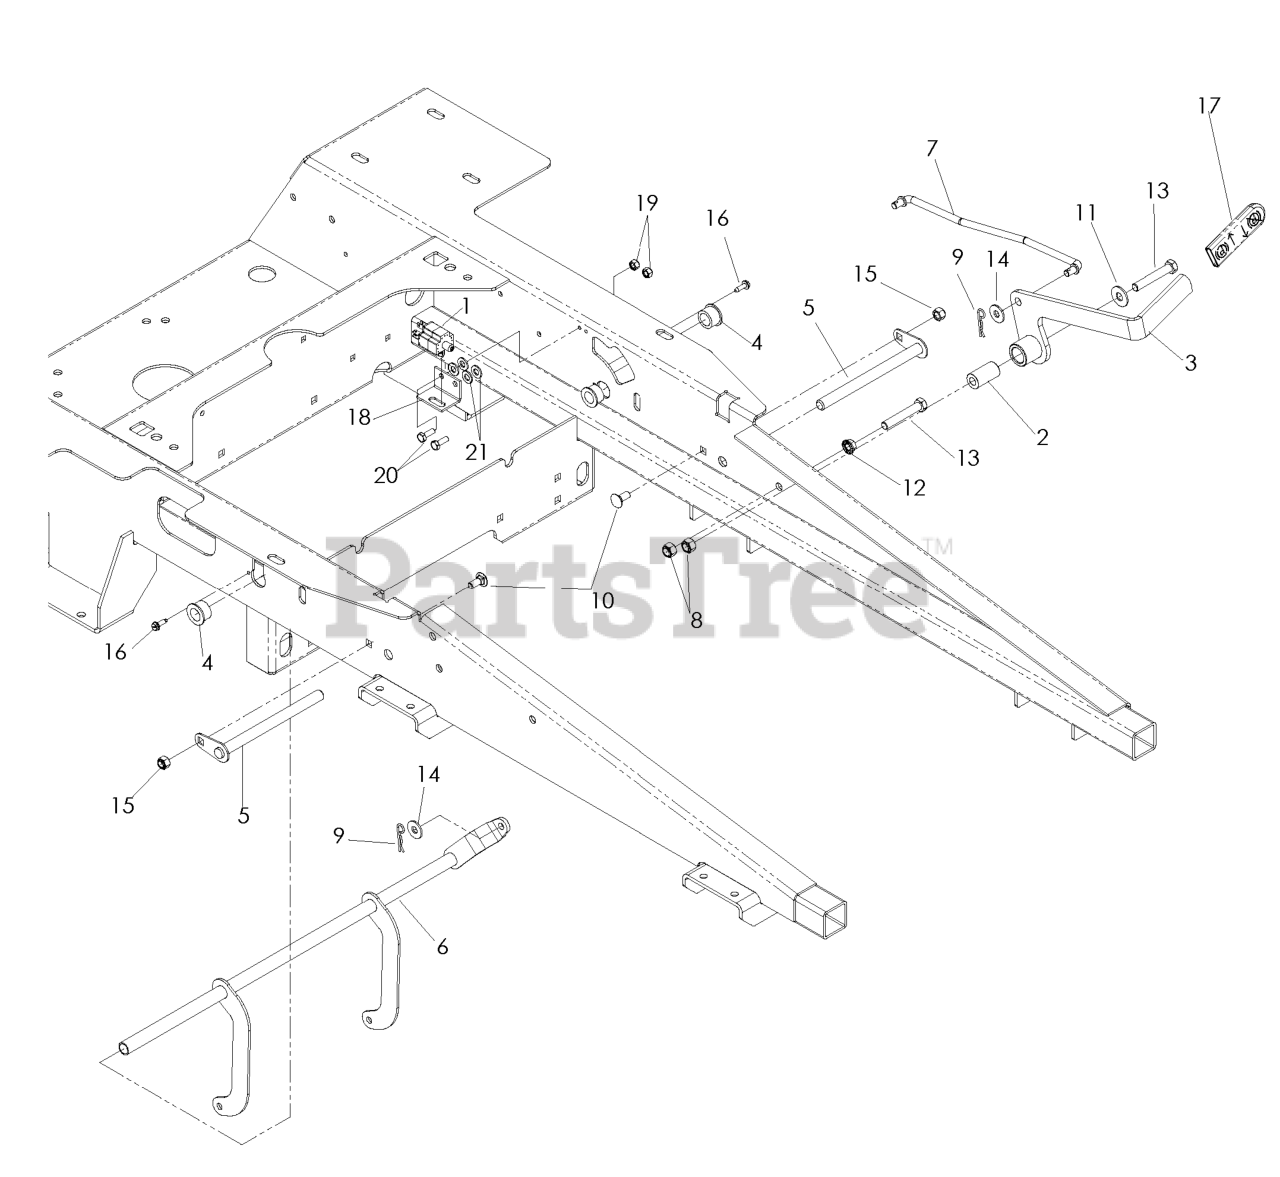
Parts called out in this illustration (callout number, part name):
1	SWITCH, BRAKE 3P
2	BUSHING, SLEEVE
3	BRAKE LEVER WLDMT
4	PLASTIC BUSHING
5	PIVOT SHAFT
6	BRAKE SHAFT
7	BRAKE LINKAGE
8	NUT 3/8-16 NYLOC
9	HAIRPIN #2
10	BOLT 5/16C X 3/4" CARRIAGE
11	WASHER 3/8 FLAT
12	NUT 3/8C WHIZ
13	HCS 3/8C X 2 1/4
14	WASHER 5/16 FLAT
15	NUT 5/16 NYLOC
16	SCREW #10 X 1/2 SELF TAPPING
17	GRIP, PARK BRAKE
18	BRACKET, BRAKE SWITCH
19	NUT.1/4-20.HEX.NYLOC.ZD
20	HCS 1/4C X 3/4 HCS
21	FLAT WASHER 5/16 SAE
